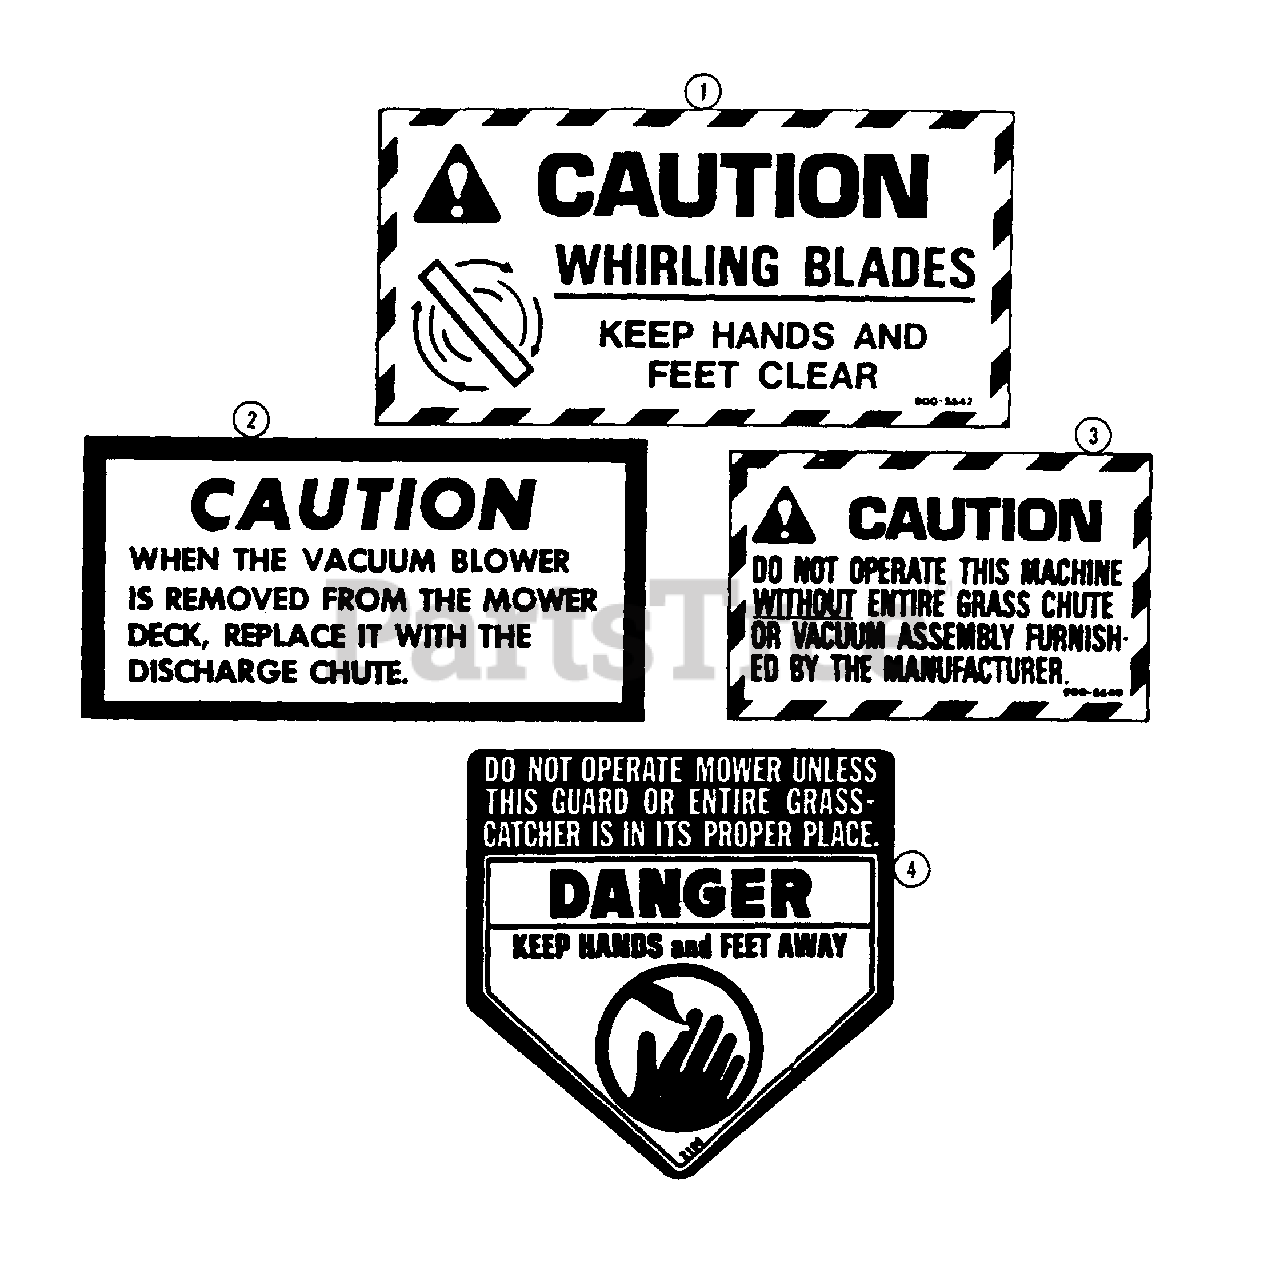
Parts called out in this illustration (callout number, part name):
1	DECAL - "Whirling Blades"
2	DECAL - "Caution" discharge chute
3	DECAL - "Caution" grass chute
4	DECAL - "Danger"
